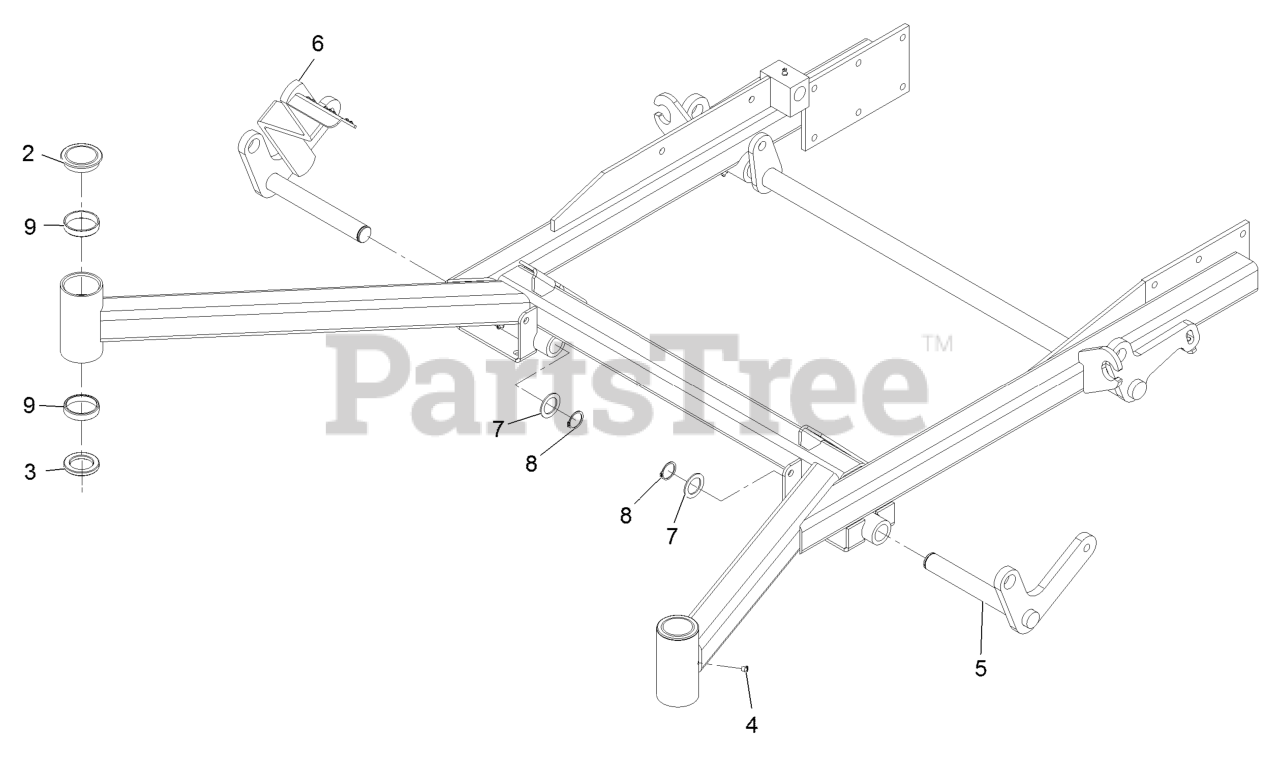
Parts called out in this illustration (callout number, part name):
2	CAP-GREASE
3	SEAL-GREASE
5	WLD,FRONT LIFT SHAFT-LH
6	WLD,FRONT LIFT W/LEVER
7	WASHER-SPACER
8	RING-RETAINING
9	CUP-BEARING
